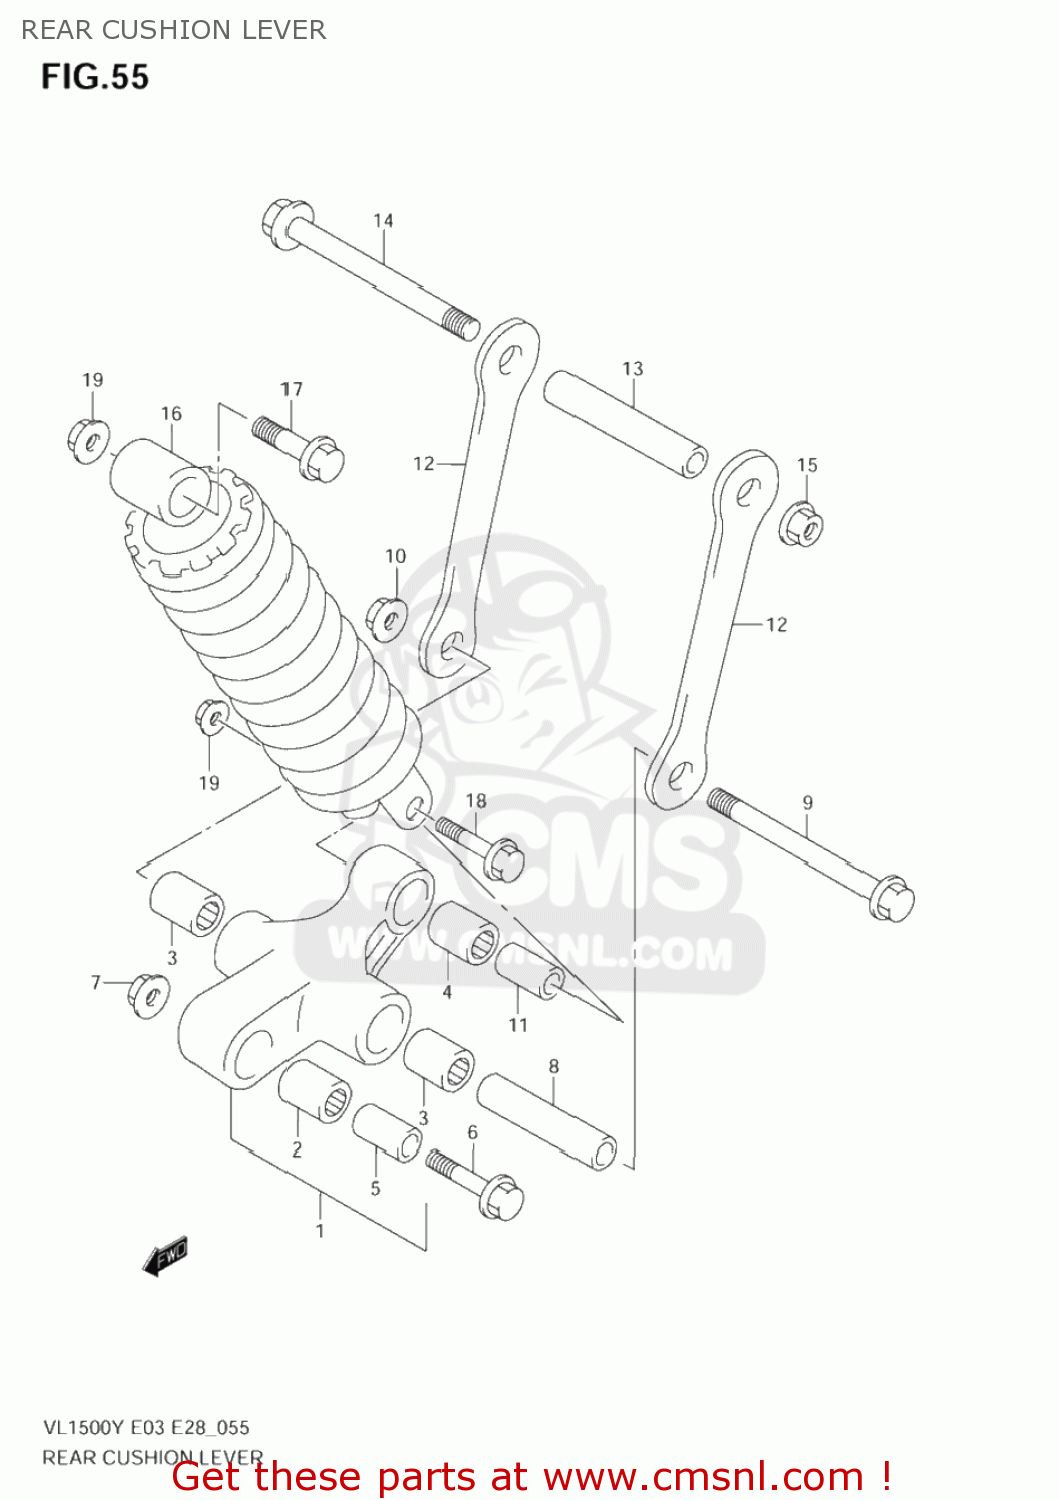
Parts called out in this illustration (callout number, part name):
1	LEVER SET,RR CUSHION
2	BEARING(20X27X32)
3	BEARING(20X27X23.5)
4	BEARING(17X24X26)
5	SPACER(14X20X34)
6	BOLT(14X66)
7	NUT
8	SPACER(14X20X99)
9	BOLT(14X129)
10	NUT
11	SPACER,RR CUSHION LEVER
12	ROD,RR CUSHION
13	SPACER(14X20X99)
14	BOLT(14X129)
15	NUT
16	ABSORBER ASSY,RR SHOCK
17	BOLT(10X50)
18	BOLT(10X54)
19	NUT
